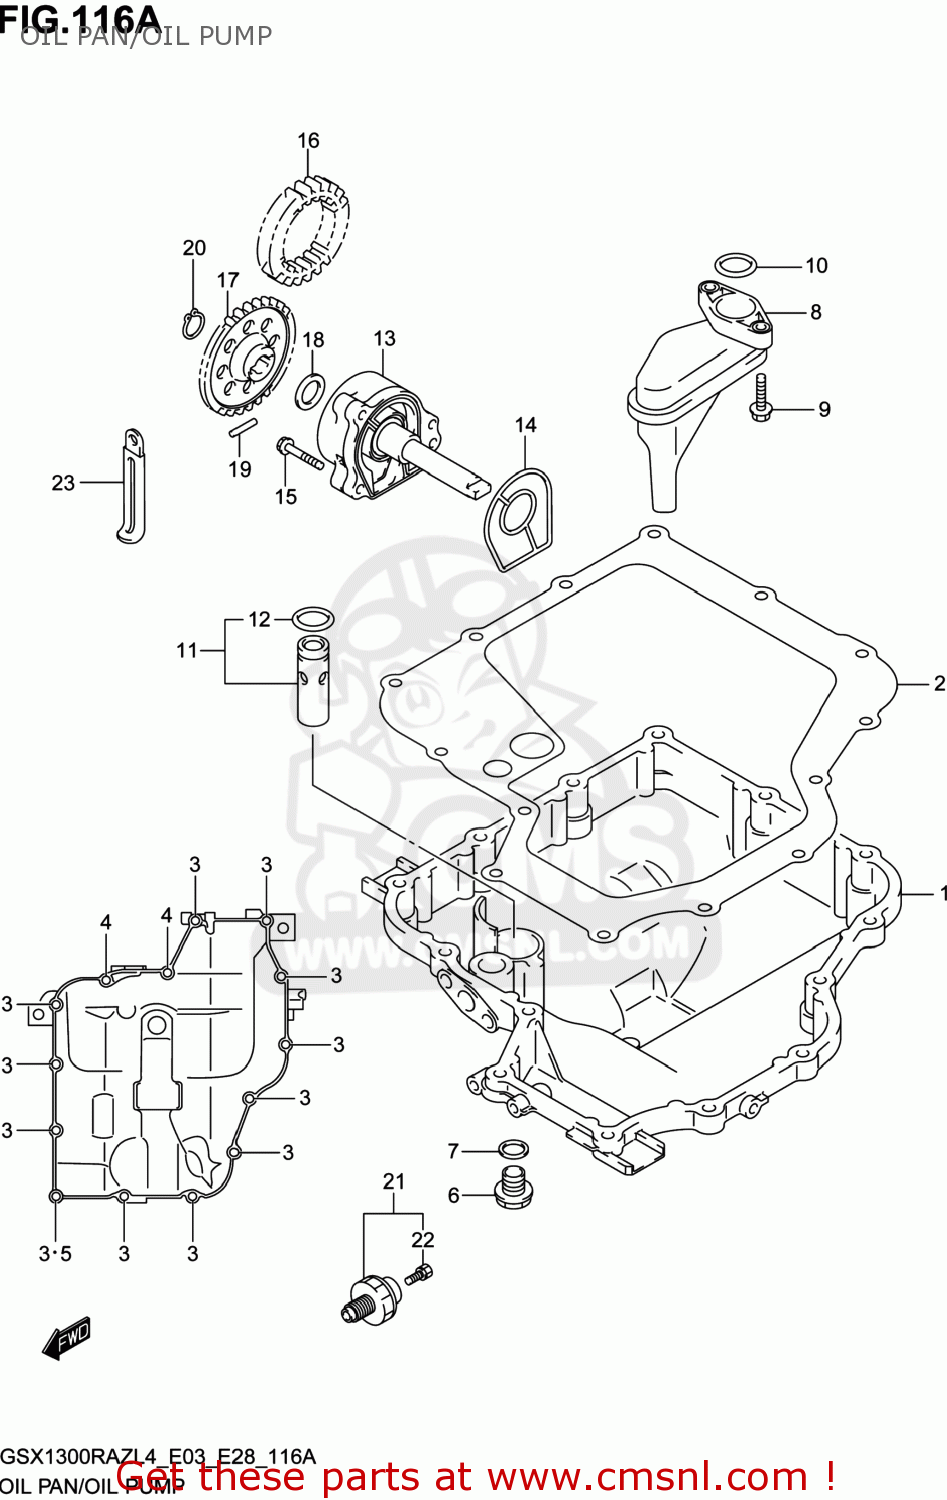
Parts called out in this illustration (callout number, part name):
1	PAN,OIL
2	GASKET,OIL PAN(ASB) (NAS)
3	BOLT
4	BOLT
5	GASKET(5.8X13X1.2) (NAS)
6	PLUG(14X20)
7	GASKET(13.8X18.8X4.8) (NAS)
8	STRAINER,ENGINE OIL
9	BOLT
10	O RING(D:2.62,ID:20.3)
11	VALVE ASSY,OIL RELIEF(7K)
12	O RING(D:1.9,ID:13)
13	PUMP ASSY,ENGINE OIL
14	O RING,OIL PUMP
15	BOLT
16	GEAR,OIL PUMP DRIVE
17	GEAR,OIL PUMP DRIVEN
18	SHIM(12X20X0.5)
19	PIN(5X18)
20	CIRCLIP
21	SWITCH ASSY,OIL PRESSURE
22	BOLT,OIL PRESSURE SWITCH
23	CLAMP(L:45)
